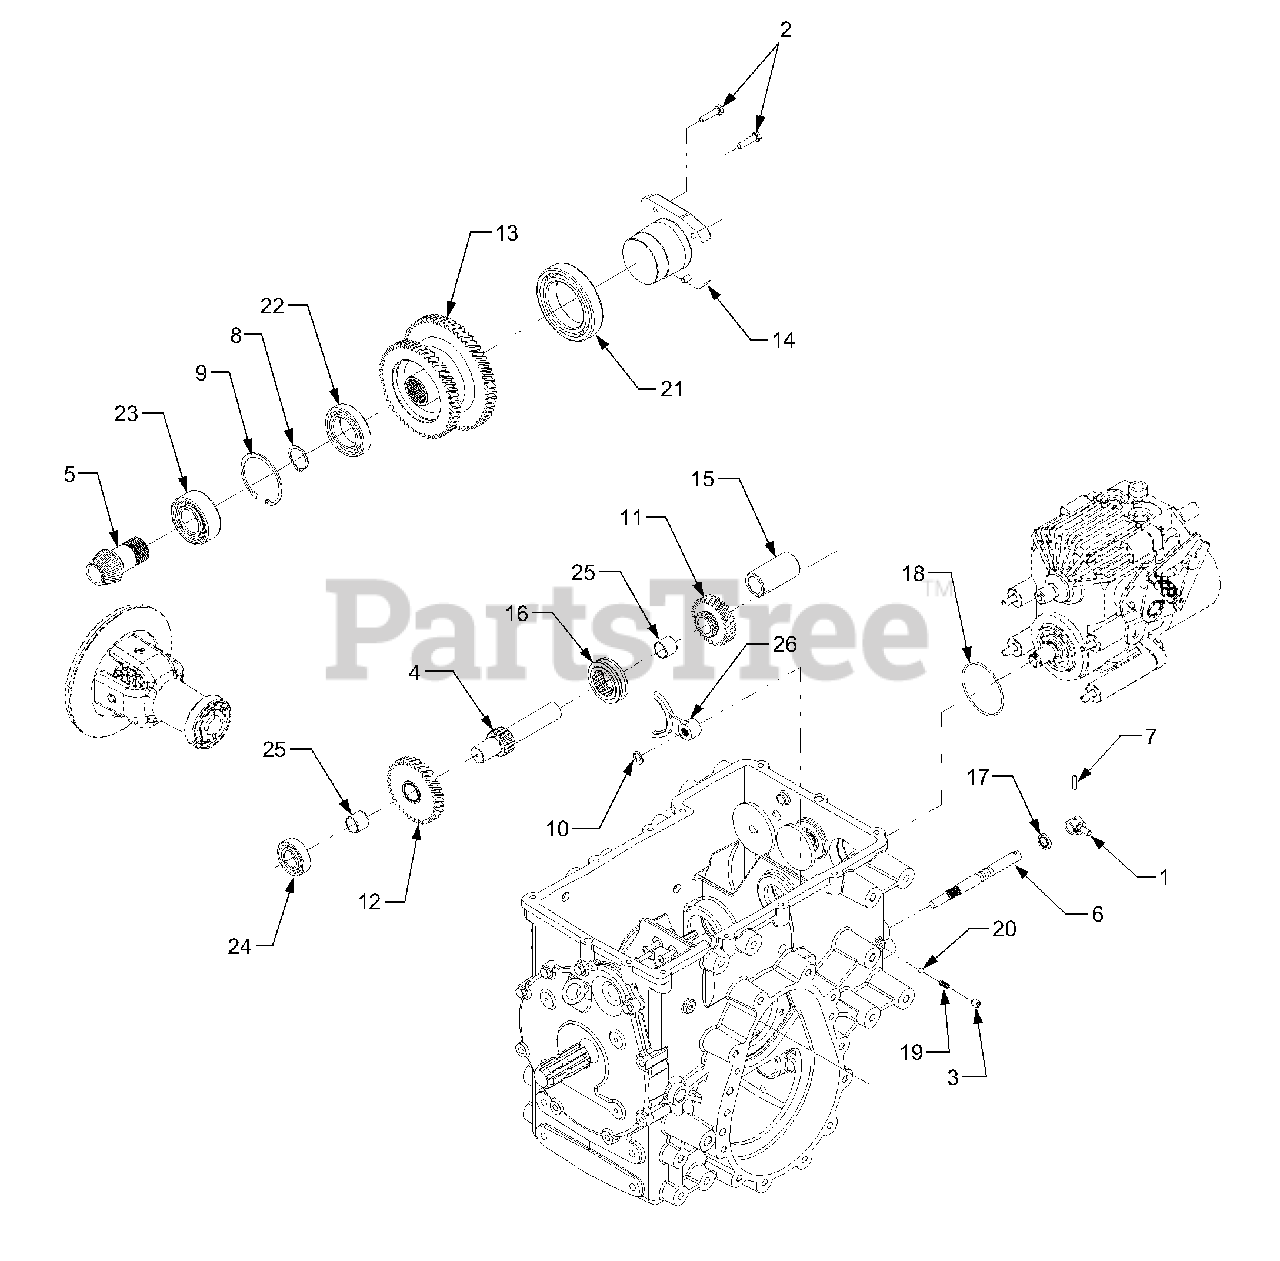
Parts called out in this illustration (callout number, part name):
1	Pin Assembly, 2 Speed
2	Screw, Hex Cap Lock, 5/16-18 x 1.25 GR5
3	Screw, Cup Set, 5/16-18 x 3/8
4	Shaft, Motor
5	Shaft, Pinion, 16T
6	Shaft, 2 Speed Actuator
7	Pin, Spirol, 3/16 x .875
8	Ring, Retaining
9	Ring, Retaining
10	Clip, Rotor
11	Gear, Drive Pinion, LO 24T:17T
12	Gear, Drive Pinion, HI 33T: 17T
13	Gear, Drive, LO:59T; HI 50T
14	Cover, Front
15	Spacer, Drive
16	Collar, 2 Speed
17	Seal, Oil
19	Spring, Detent
20	Ball, Detent
21	Bearing, Ball
22	Bearing, Ball
23	Bearing, Angular Contact Ball
24	Bearing, Ball
25	Bearing, Sleeve
26	Yoke, 2 Speed
